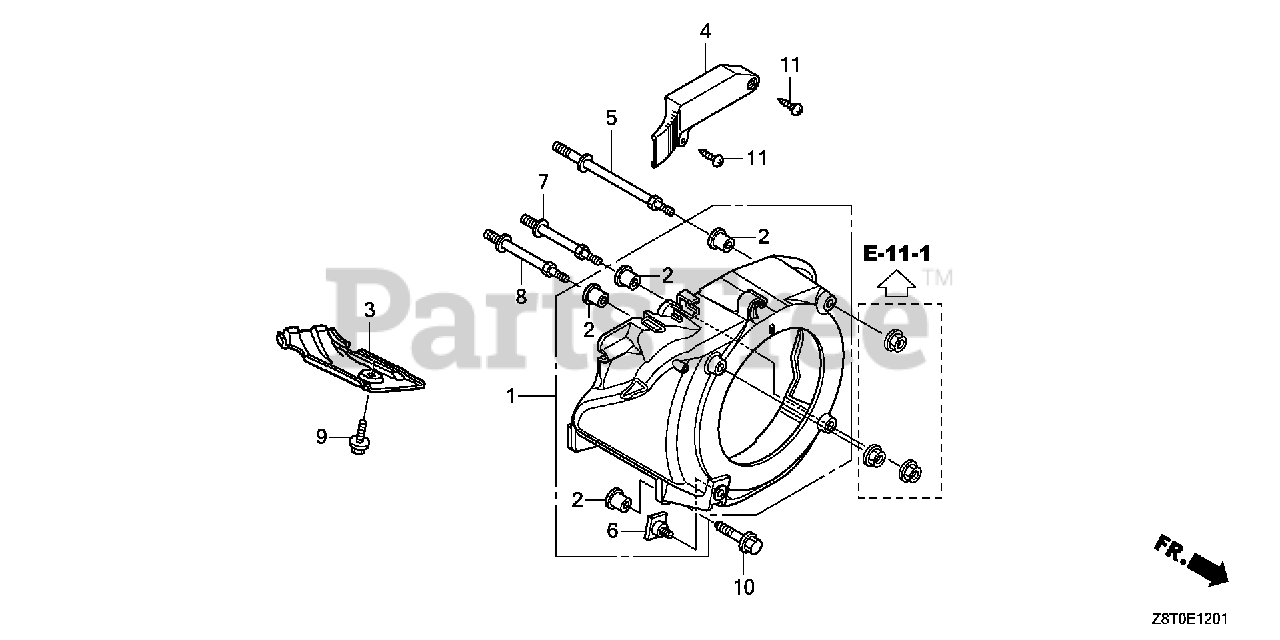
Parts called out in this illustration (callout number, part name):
1	COVER, FAN *NH1* (BLACK)
1	COVER, FAN *R280* (POWER RED)
2	COLLAR, FAN COVER
4	COVER, ELECTRONIC PARTS
5	BOLT, STUD (SEL)
6	BOLT, SPECIAL (6MM)
7	BOLT, STUD
8	BOLT B, STUD
9	BOLT, FLANGE (6X12) (CT200)
10	BOLT, FLANGE (6X25) (CT200)
11	SCREW, TAPPING (5X20)
